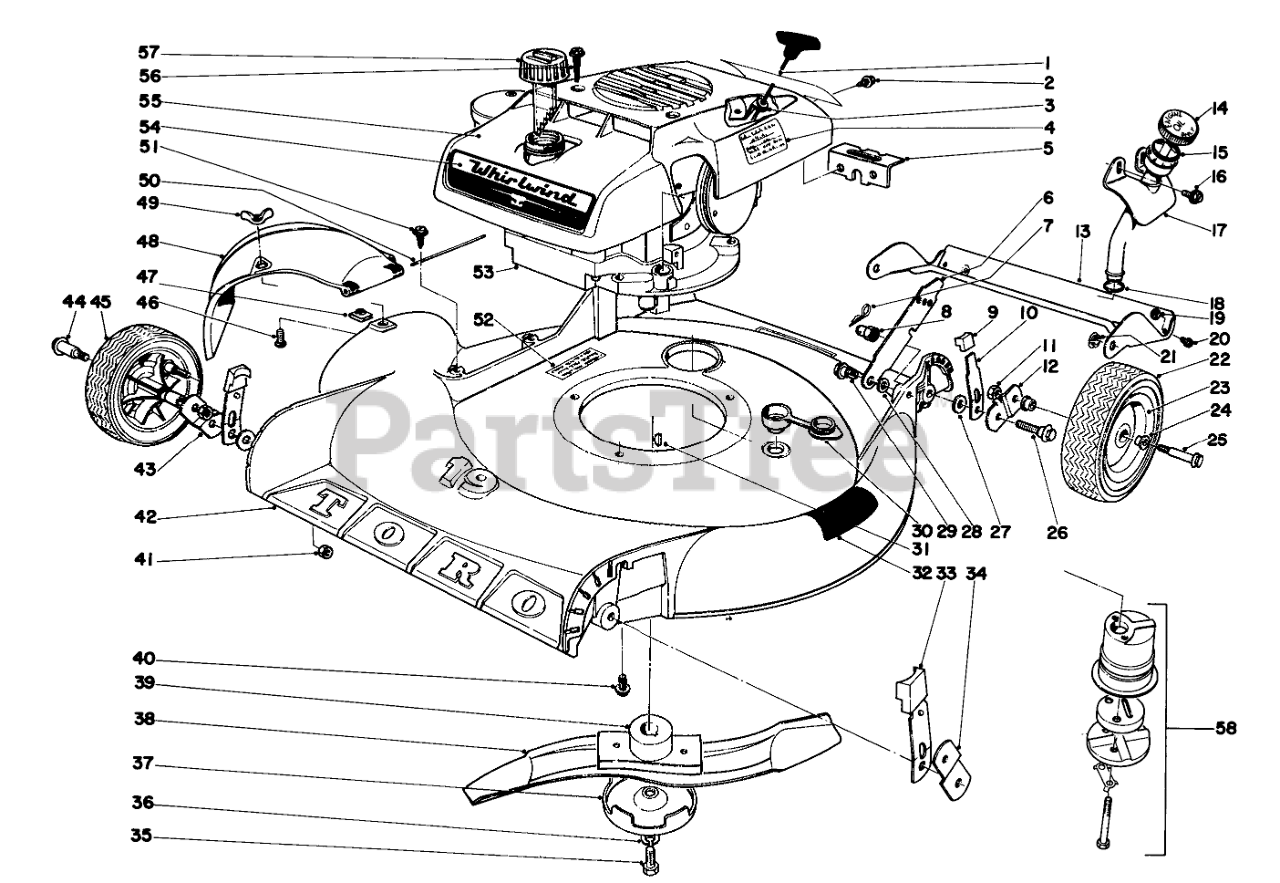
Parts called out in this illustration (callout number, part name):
1	Decal
2	Self Tapping Screw
3	Bracket,Recoil
4	Decal,Start
5	Bracket
6	Latch
7	Hairpin Cotter
8	Nut
10	Spring Arm
11	1/4-28 NYLOK NUT
12	Pivot Arm
13	Rear Safety Shield
14	Dipstick
15	O-Ring
17	Tube, Oiler
18	O-RING
19	NUT-JAM
20	Screw-Nylon
21	Nyliner
22	8 TIRE
23	Wheel Assembly (Incl. Ref.24)
24	Bushing
25	Wheel Bolt
26	Pivot Screw
27	WASHER-PIVOT
28	SPACER
29	SCREW-SHOULDER
30	Washer Plug
31	KEY-WOODRUFF
33	ARM KNOB
34	Pivot Arm
35	SPECIAL SCREW
36	WASHER-LOCK
37	Scalp Cup
38	Blade
39	BLADE RETAINER WA
40	Screw
41	Nut
42	Housing
43	Pivot Arm
47	NUT-SPEED
48	Deflector
49	NUT-WING SPECL
50	HINGE PIN
51	Screw
52	Decal
53	Engine, Recoil
54	Decal
55	Shroud
56	SCREW-HWH
57	Gas Cap
58	MUFFLER KIT
